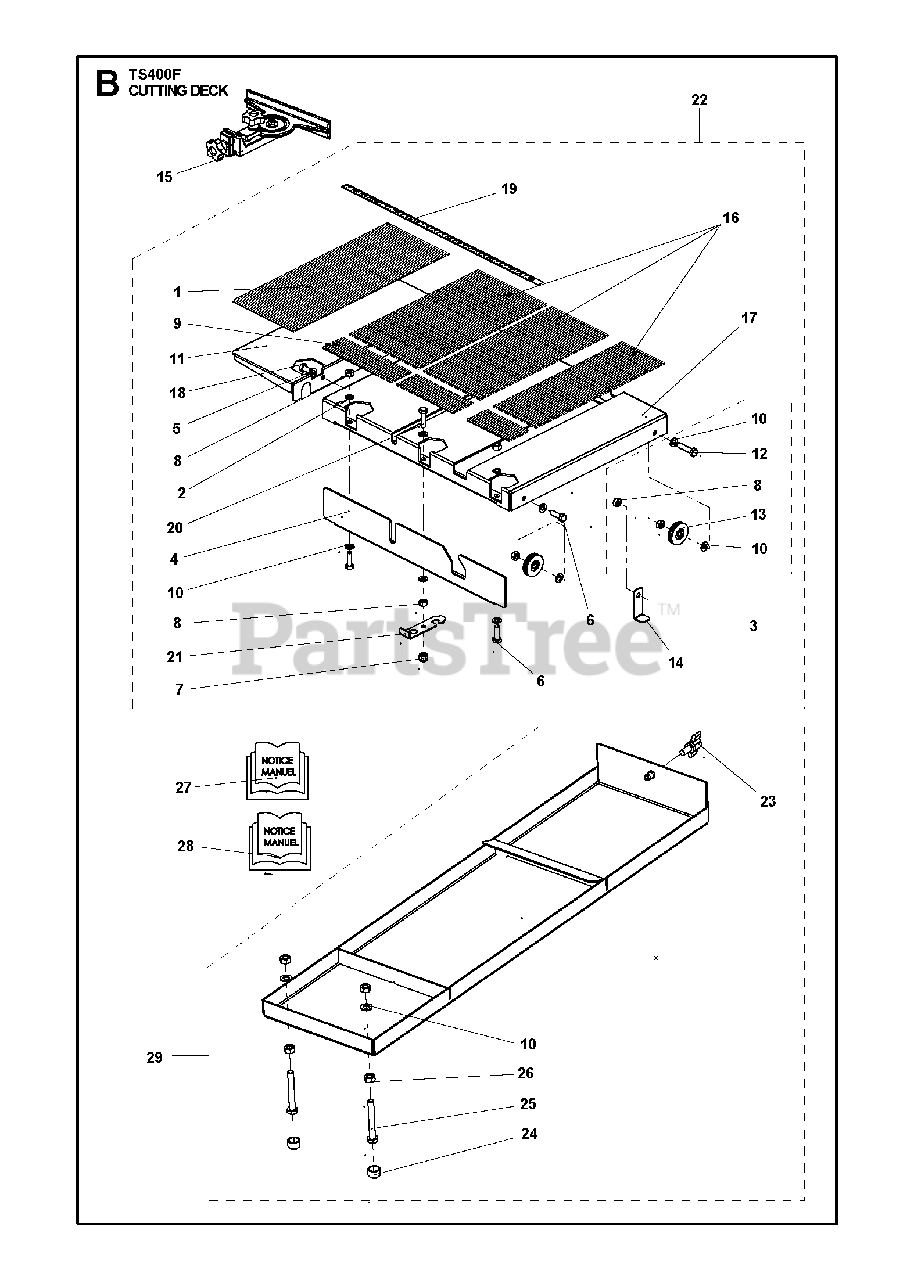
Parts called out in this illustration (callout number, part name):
5	WASHER
7	HEXAGON LOCKING NUT
8	HEXAGON NUT
9	TAPIS AV STRIE ADHESIF/TS400F
10	WASHER
14	RETENUE DE TABLE/TS 350 F
16	TAPIS AR STRIE ADHESIF/
18	SCREW EHHM
19	RULER, MIDDLE, TS400FTS400F
19	RULER, RIGHT, TS400FTS400F
23	GALET GP/34 8X15 6310075/
24	CHAPEAU GPN 1000/893/
26	HEXAGON NUT
28	ILLUSTRATED PARTS LIST
29	TANK UNIT ASSYCompl *
